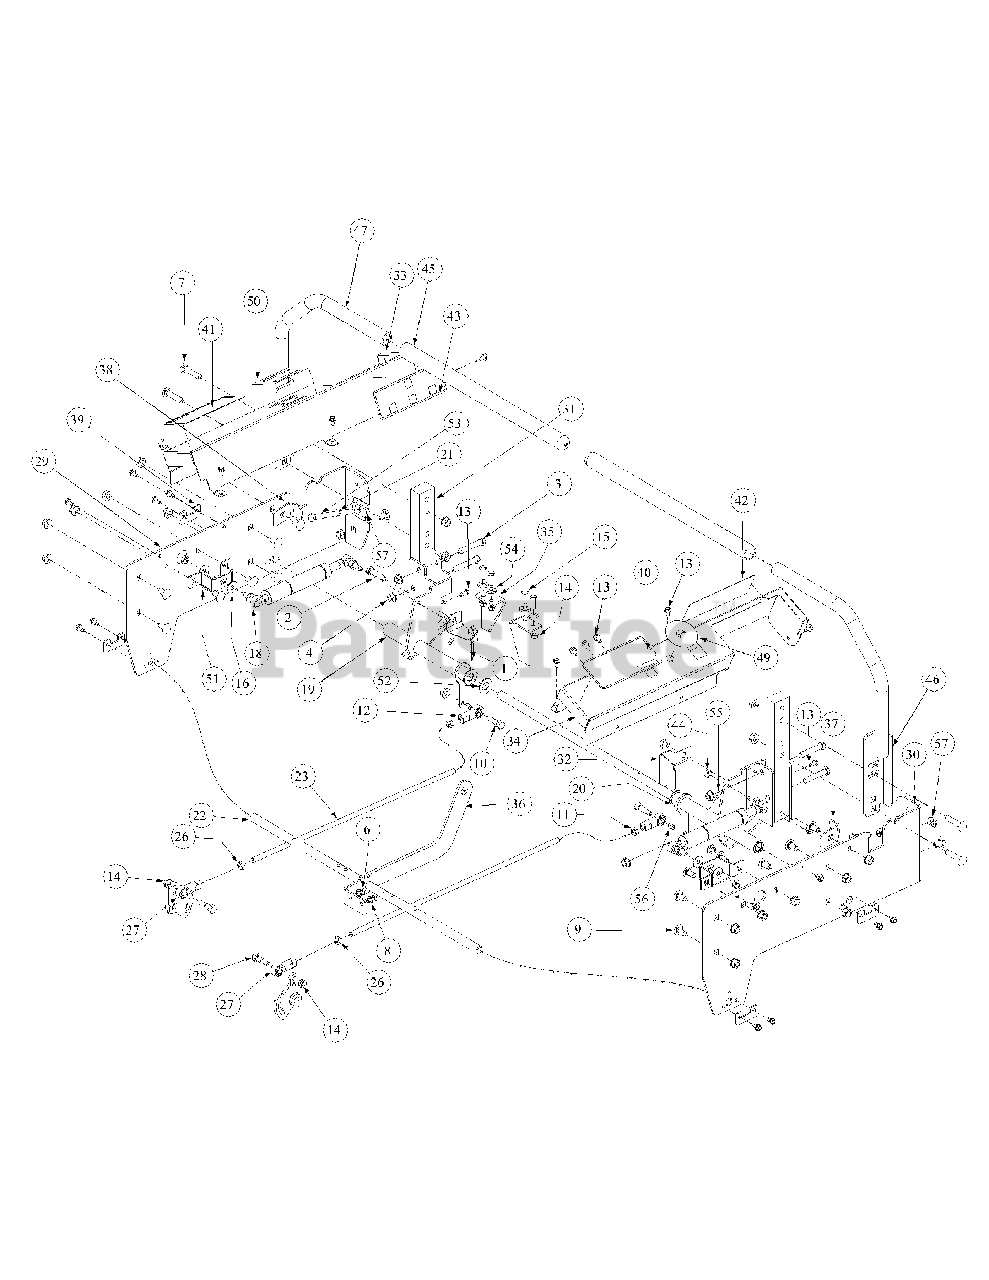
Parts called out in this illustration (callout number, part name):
1	Cotter Pin 5/32 x 1-1/2
2	HHCS, 3/8-16, 2.00
3	HHCS, 3/8-16, 2.25
4	Hex Nut, 3/8-16, Lock Flange
6	HHCS, 1/4-20, .620
7	Hex Carriage Screw, 3/8-16, 1.75
8	Lock Washer, 1/4 Zinc
9	Carriage Bolt, 3/8-16 x .75
10	Capscrew, 3/8-16 x 1-3/4
11	Hex Jam Nut, 3/8-24
12	B/Joint, 3/8-24, Right Hand Female
13	Screw, TT, 1/4-20, 0.5, Hex Index Washer
14	Nut, Lock, Hex Flange, 5/16-18
15	Hex, Cap Screw, 5/16-18 x 3/4
16	Belle Washer, .325 x .930 x .045
18	Cylinder Return to Neutral
19	Hub Assy, Control LH Bearing
20	Hub Assy, Control RH Bearing
21	Nut, 3/8-16, Jam
22	Shaft Mounting Belle Crank
23	Rod Connector 3/8 OD x 10.125
26	Nut, 3/8-24, Jam, LH Third
27	B/Joint, 3/8-24, LH Female
28	Screw, Shoulder Control Rod
29	Side Panel, Control, Left
30	Side Panel, Control, Right
31	Mounting Handle
32	Lever, Safety Switch
33	Control Panel, LH
34	Control Panel, RH
35	Switch Mounting Bracket, Lapbar
36	Link Mounting Control Shaft, Bracket
39	Holder Shaft, Park Brake
40	Decal , Right Hand Console
41	Decal, Left Hand Console
42	Decal Right Hand Control
43	Decal, Left Hand Control
44	Nut, Hex, Center Lock, M8
45	Grip, 1.0
46	Lapbar, Weldment, Right Handle
47	Lapbar, Weldment, Left Handle
49	Label, Ignition, 2.5 Diameter
50	Label, Control, Throttle and Choke
51	Bracket Assembly, Mount Dampener
52	Flat Washer, 5/8 Nylon
53	HHCS, 3/8-16, 3.00
54	Flat Washer, 5/16
55	Grease Fitting, 90°.
56	Spacer, .385ID x .625 OD x >50 Lg
57	U-Nut, 3/8-16, .75
